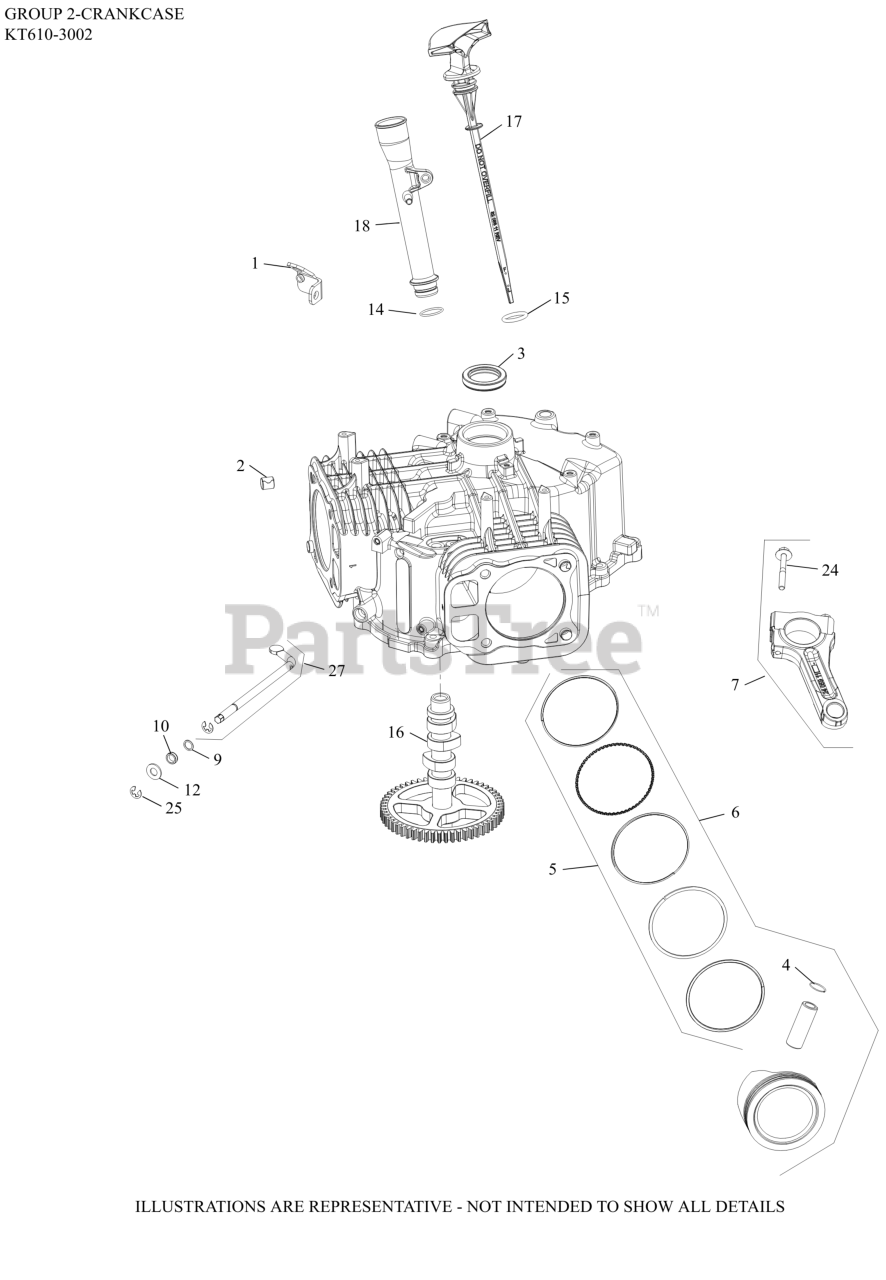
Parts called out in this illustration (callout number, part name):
1	BRACKET, OIL FILL TUBE
2	PIN, LOCATING
3	SEAL, OIL (HELIX LIP)
4	RETAINER, PISTON PIN
5	RING SET(STD)STYLE B-1.2mm Tp RING THICK
6	KIT, PISTON & RINGS ASSY
7	ROD, ASSEMBLY CONNECTING
9	WASHER, FLAT 11/32"
10	SEAL, GOVERNOR CROSS SHAFT
12	WASHER, FLAT 9 MM
16	CAMSHAFT ASSEMBLY (PLASTIC GEAR)
17	DIPSTICK, ASSY
18	TUBE ASSEMBLY, OIL FILL
24	KIT, ROD BOLTS
25	CLIP, RETAINER GOVERNOR SHAFT
27	KIT, CROSS SHAFT
